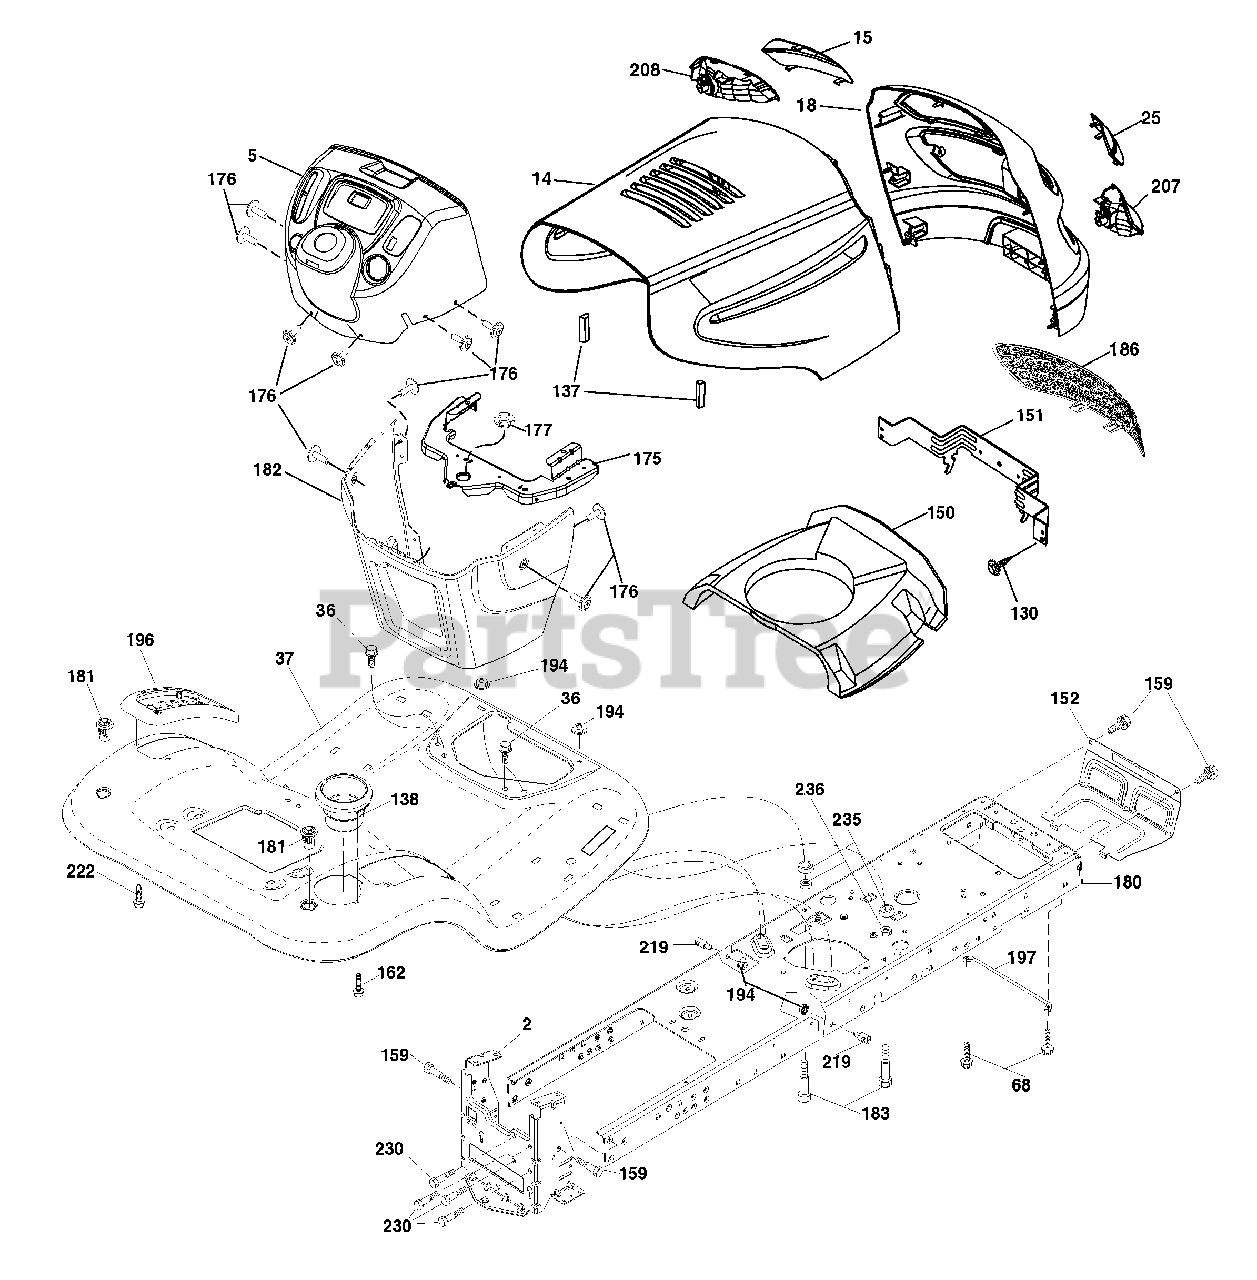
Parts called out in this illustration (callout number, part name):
2	Drawbar
5	Dash
14	Hood
15	Lens Grille LH
18	Grille
25	Lens Grille RH
36	Screw 5/16-18 x 3/4
68	Screw Thdrol 5/16-18 x 1/2
130	Screw 10 x 3/4 Single Lead-Hex
137	Bumper Hood
138	Cupholder
150	Duct Heat Hood
151	Bracket Pivot
152	Shield Browning/Debris
159	Screw Hexwsh Thdrol 3/8-16 x 3/4
162	Screw Hex Wsh Hi-Lo 1/4 x 1/2
175	Crossmember
176	Screw 10-24 x 5/8 Wshd Qdrx
177	Bushing Steering
181	Bushing Mtg. Fender Crgo.
182	Dash Lower
183	Bolt Fin Hex 5/16-18 x 1-1/4
186	Insert Grille
194	Nut Lock Hex Flange 5/16-18
196	Console Asm. Deck Lift
197	Rod Pivot Chassis
207	Bezel Grille RH
208	Bezel Grille LH
219	Stud Fastener
222	Screw Thd Roll 1/4-20 x 5/8
230	Bolt Shoulder 5/16-18
235	Spacer Fender
236	Nut center Lock 5/16-18
